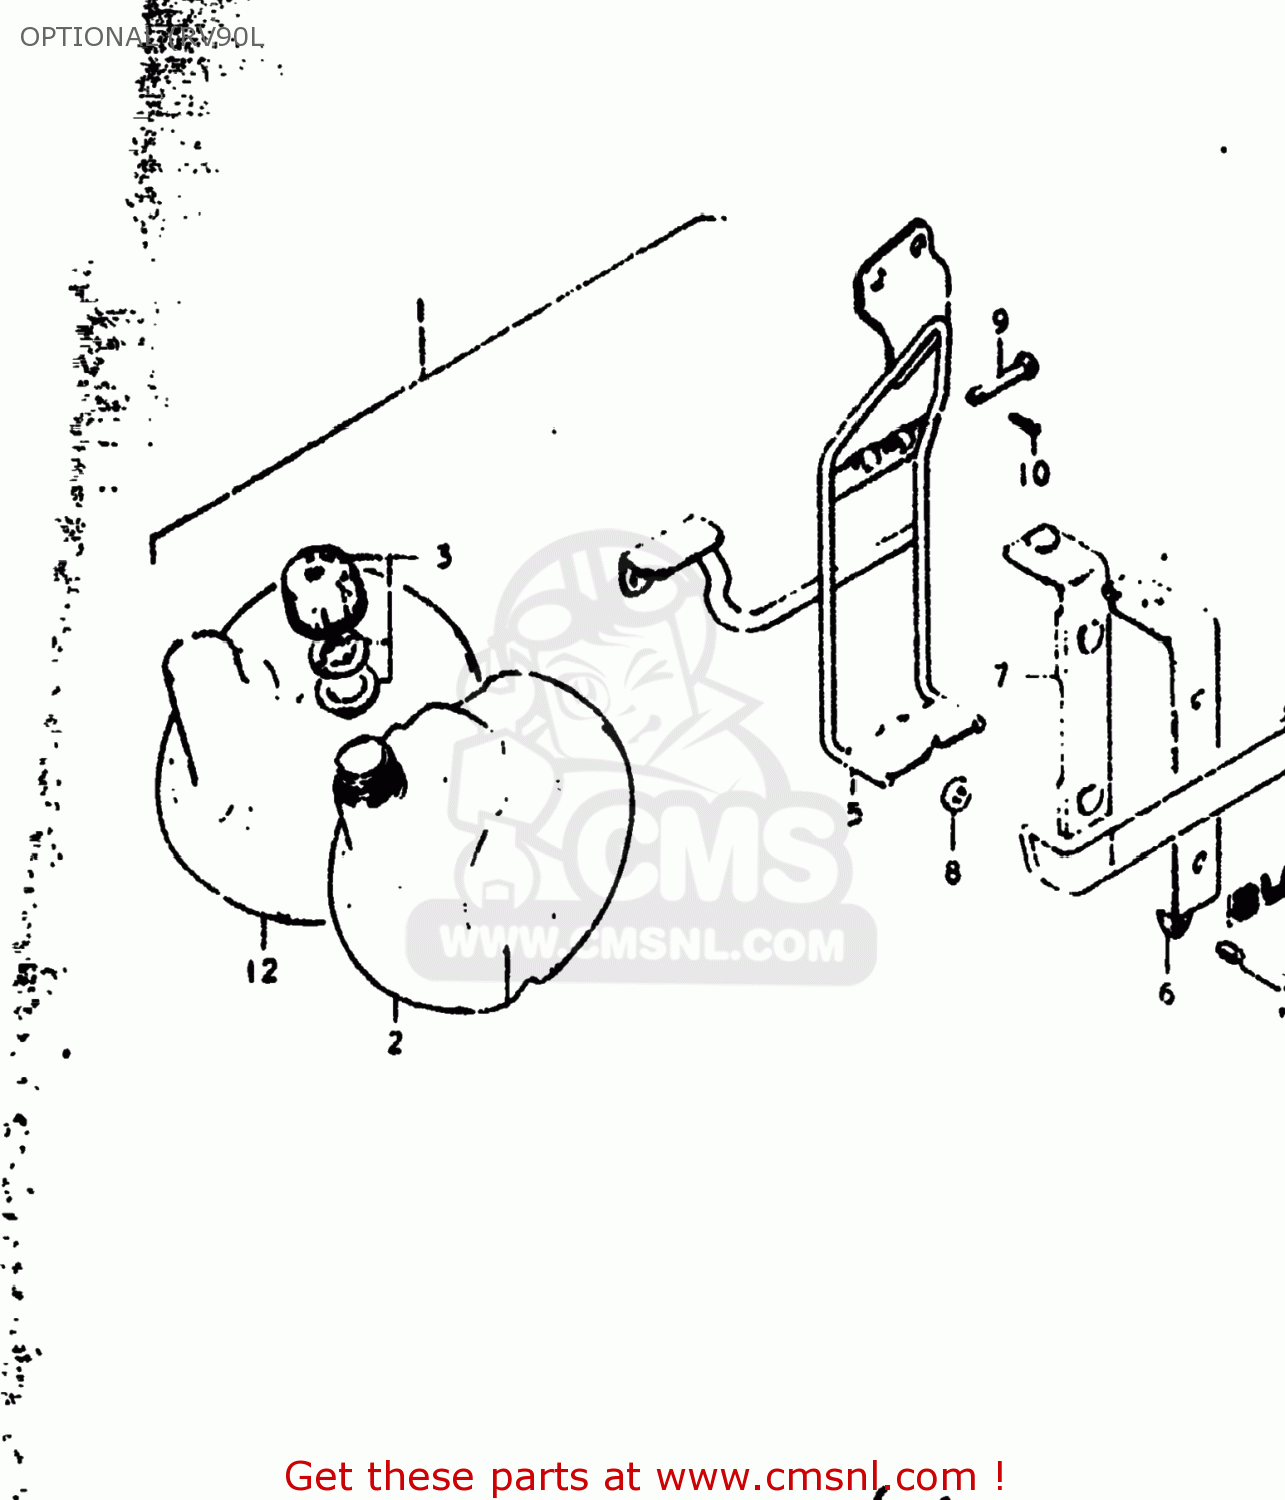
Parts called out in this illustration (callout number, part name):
1	TANK ASSEMBLY,FUEL
2	TANK ASSEMBLY,FUEL
3	TANK ASSEMBLY,FUEL
4	KNOB,FRAME COVER,L
5	CARRIER,SUB FUEL TANK
8	NUT
9	PIN
10	PIN
11	EMBLEM,SUB FUEL TANK
